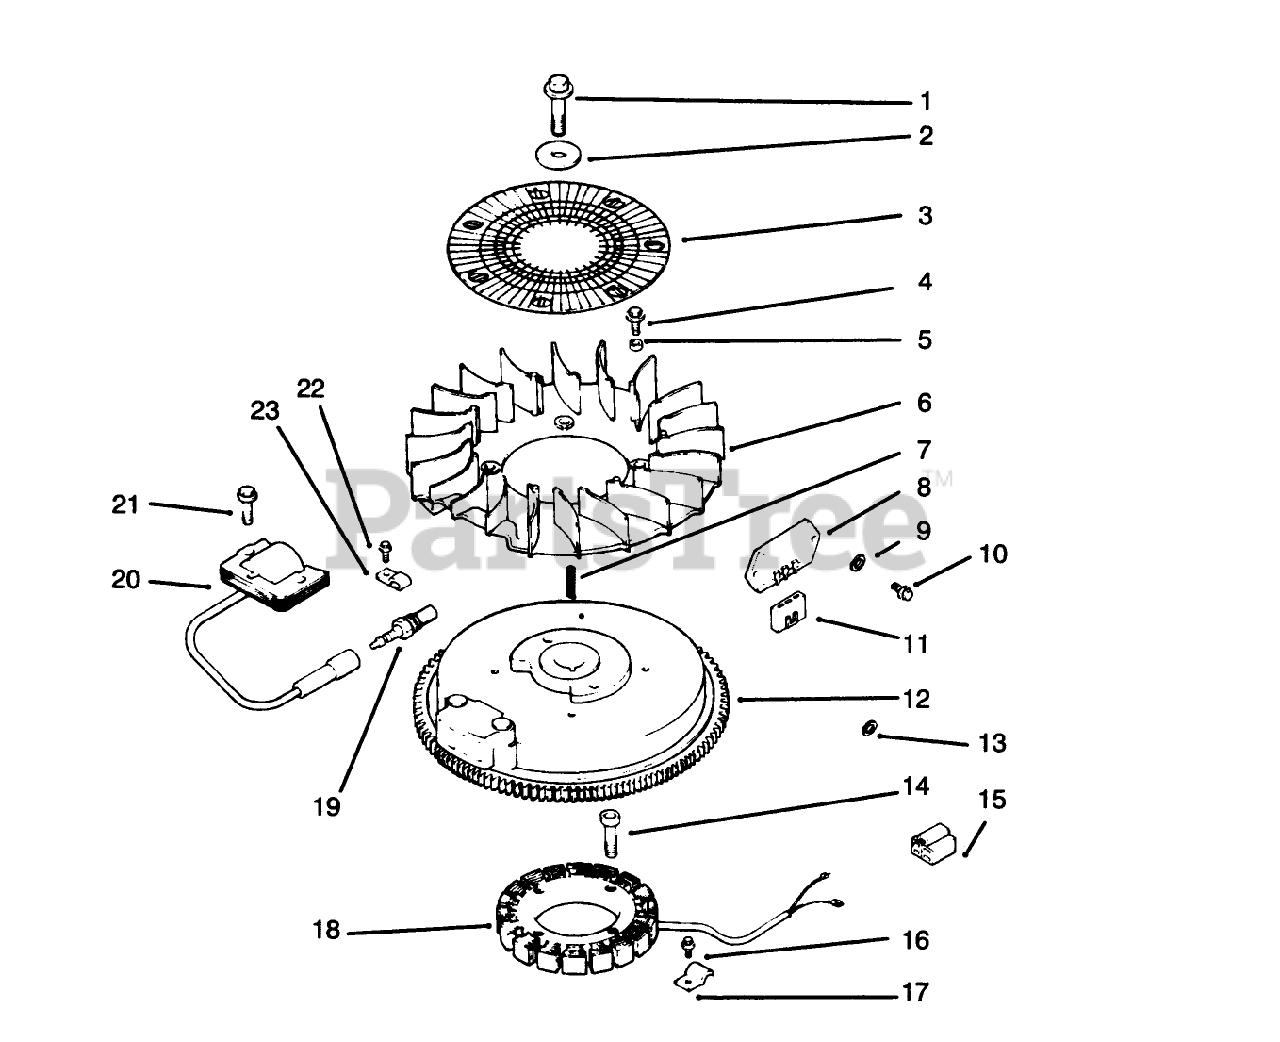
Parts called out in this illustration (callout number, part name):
1	Screw
3	Screen-Grass (Only On: 72042, 72063, 72062, 72043)
5	Spacer-Fan
6	Fan (Only On: 72042, 72063, 72062, 72043)
8	Rectifier-Regulator (Only On: 72042,72043,72062,72063)
9	Washer-Lock (Only On: 72042, 72063, 72062, 72043)
11	Connector
12	Flywheel ASM (Only On: 72042, 72063, 72062, 72043)
13	Washer-Flat (Only On: 72042, 72063, 72062, 72043)
15	Connector
17	Clip-Stator Harness (Only On: 72042, 72063, 72062, 72043)
18	Stator-15 amp
19	Spark Plug
20	Module-Ignition (Only On: 72042,72043,72062,72063)
